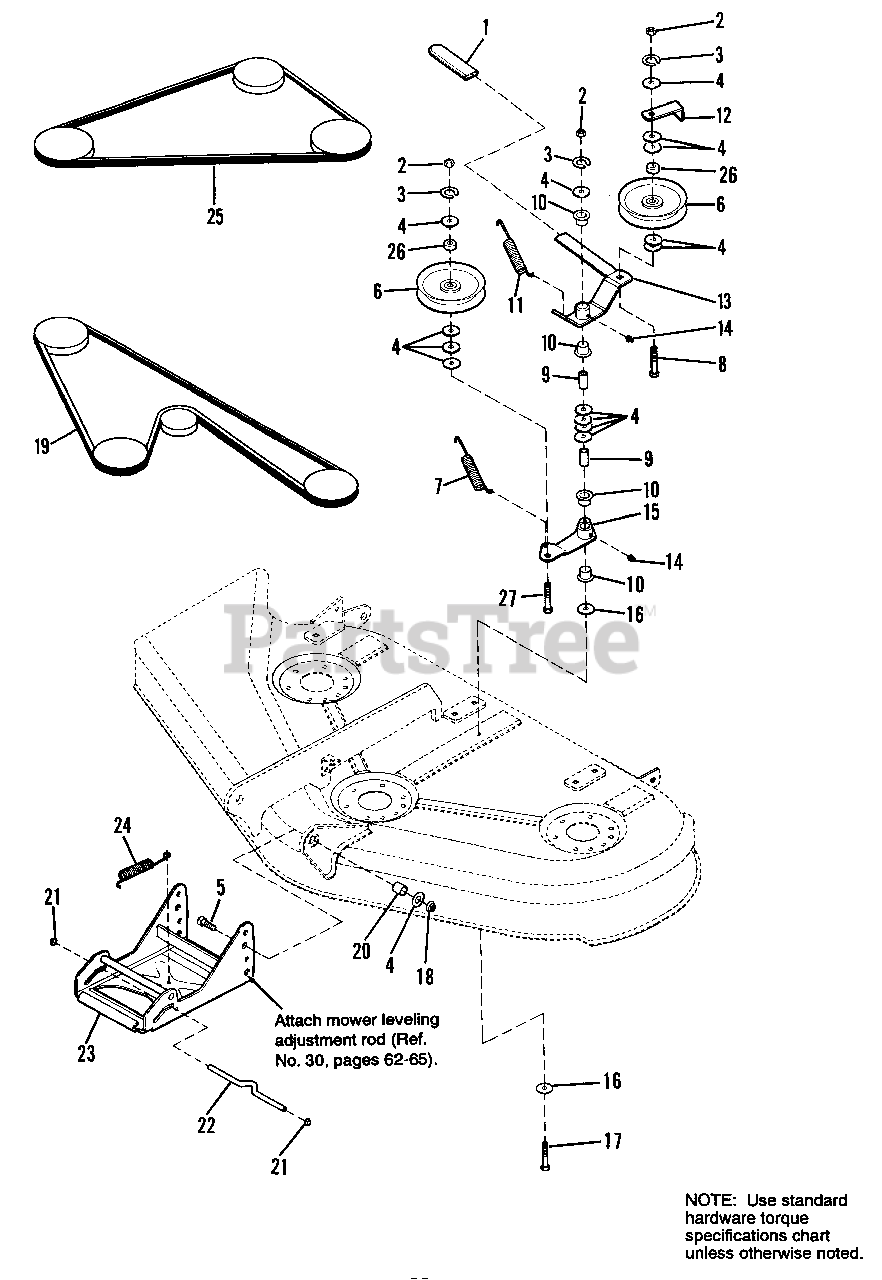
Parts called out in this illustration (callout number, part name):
1	GRIP, Lever
2	NUT, Hex, 3/8-16
3	LOCKWASHER, 3/8
4	WASHER, 5/16
5	CAPSCREW, Hex Hd., 3/8-16 x 1-1/2
6	PULLEY ASSY.
8	CARRIAGE BOLT, 3/8-16 x 1-3/4
12	IDLER, Stop
13	LEVER ASSY, Idler (Incl. Qty 2, Ref. No. 10)
14	GREASE FITTING
15	LEVER ASSY., Idler Arm (Incl. Qty 2, Ref. No. 10)
16	WASHER
17	CAPSCREW, Hex Hd., 3/8-16 x 3-1/2
18	NUT, Hex, Lock, 3/8-16
19	V-BELT, Deck Drive (44")
19	V-BELT, Deck Drive (50")
21	NUT, Push On
23	HITCH ASSY.
25	V-BELT, Mower Drive (44")
25	V-BELT, Mower Drive (50")
27	CARRIAGE BOLT, 3/8-16 x 1-1/2
